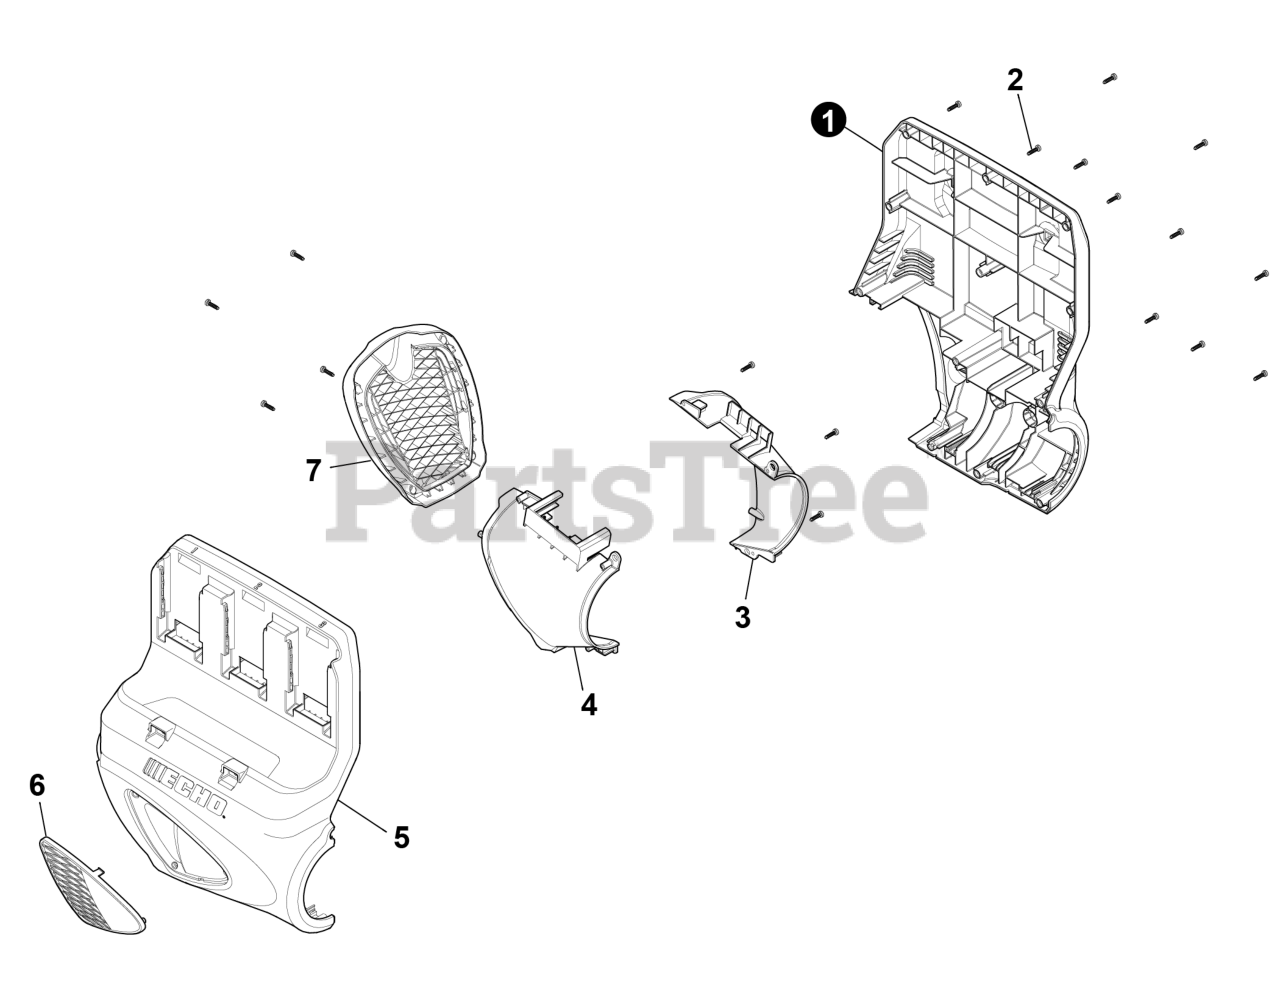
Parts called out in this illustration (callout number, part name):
1	COVER,REAR
3	DUCT,RIGHT AIR
4	DUCT,LEFT AIR
5	COVER,FRONT
6	COVER,DECORATIVE
7	COVER,AIR INTAKE
